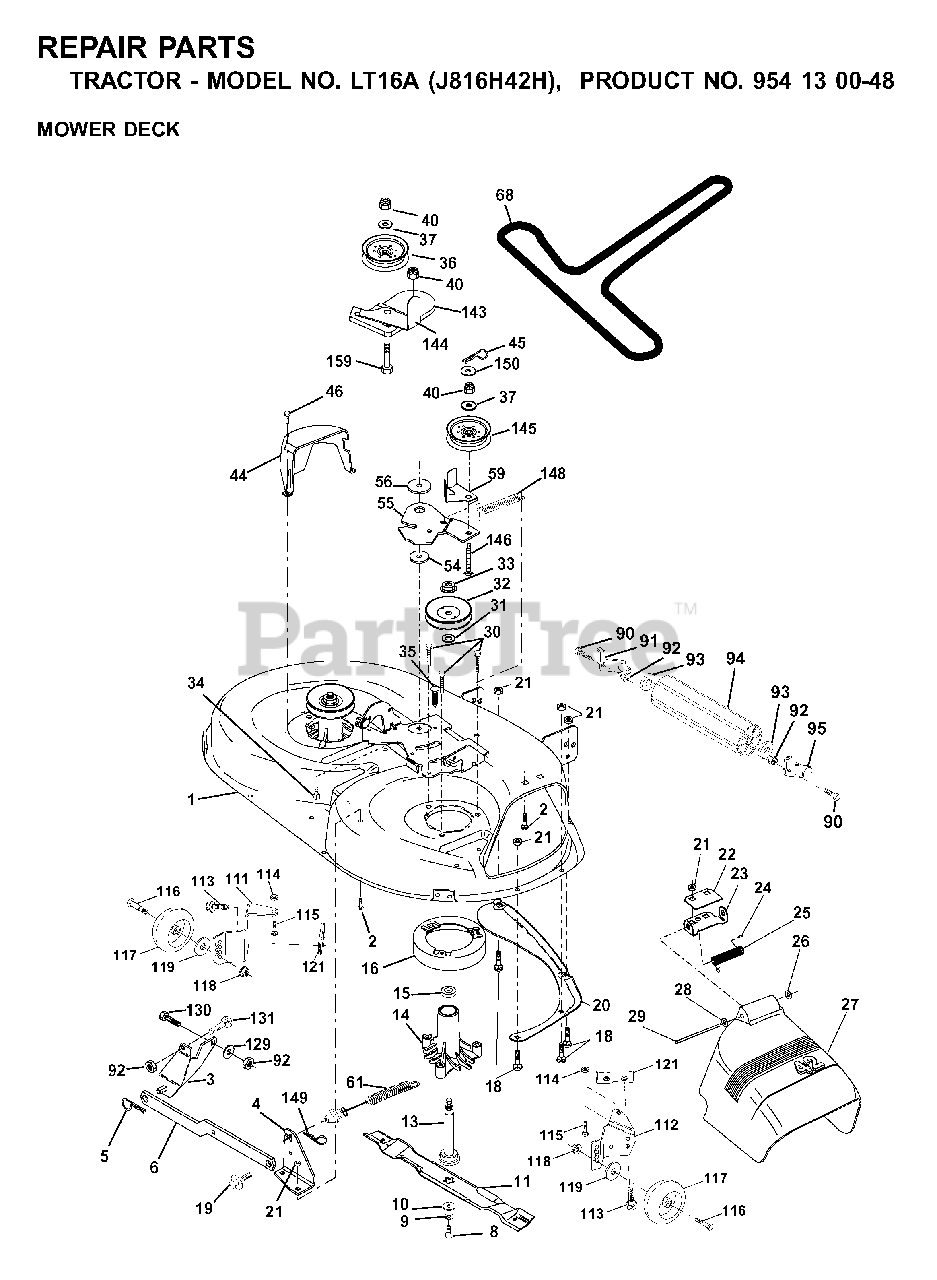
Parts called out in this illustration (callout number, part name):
1	42" DECK KIT
2	BOLT
3	BRKT ASM SWAY BAR
4	BRACKET SWAY BAR 42" DECK
5	RETAINER-SPRNG RB
6	REAR SUSP ARM
8	BLADE BOLT
9	LOCKWASHER
10	WASHER.BLADE
11	BLADE 42"
13	SHAFT ASM VENT
14	HSG MANDREL
16	STRIPPER
18	BOLT
19	BOLT SHD 5/16-18
20	BAFFLE.VORTEX
21	LOCKNUT
22	STIFFENER BRACKET
23	DEFLECTOR BRACKET
24	CAP-SLEEVE LT
25	SPRING TORSION
26	NUT PUSH M
27	SHIELD DEFLECTOR
28	WASHER
29	ROD.HINGE
30	SCREW THDROL ROLLING WASHER HD
31	WASHER
32	PULLEY/MANDREL
33	NUT
34	BOLT
35	FASTENER.XMAS.TREE
36	FLAT IDLER PULLEY
40	LOCKNUT
44	GUARD MANDREL LH BLACK
45	RETAINER M
46	SCREW.1/4-20X5/8
54	HARDENED WASHER
55	ARM IDLER 42" MOWER LT/YT
56	SPACER.RETAINER.MOWER
59	GUARD, BELT
61	SPRING EXT ELEC CLUTCH
68	BELT V SECONDARY
90	BOLT
91	BRACKET LH (A)
92	NUT
94	NOSE ROLLER
95	BRACKET RH (B)
111	BRACKET WHEEL GAUGE LH 42" DK
112	BRACKET WHEEL GAUGE RH 42" DK
114	NUT
115	BOLT
117	WHEEL.GAUGE.STANDARD
118	LOCKNUT
119	WASHER
121	BRACKET.EXTRD.GWL
129	WASHER
130	BOLT
131	BOLT D
143	BRACKET, ARM IDLER
144	KEEPER.BELT.42".CLUTCH.CABLE
145	PULLEY
146	BOLT, CARRIAGE IDLER BLACK
148	IDLER RETURN SPRING
149	SPRING.RETAINER.YELLOW.ZINC
150	WASHER PM
159	BOLT
